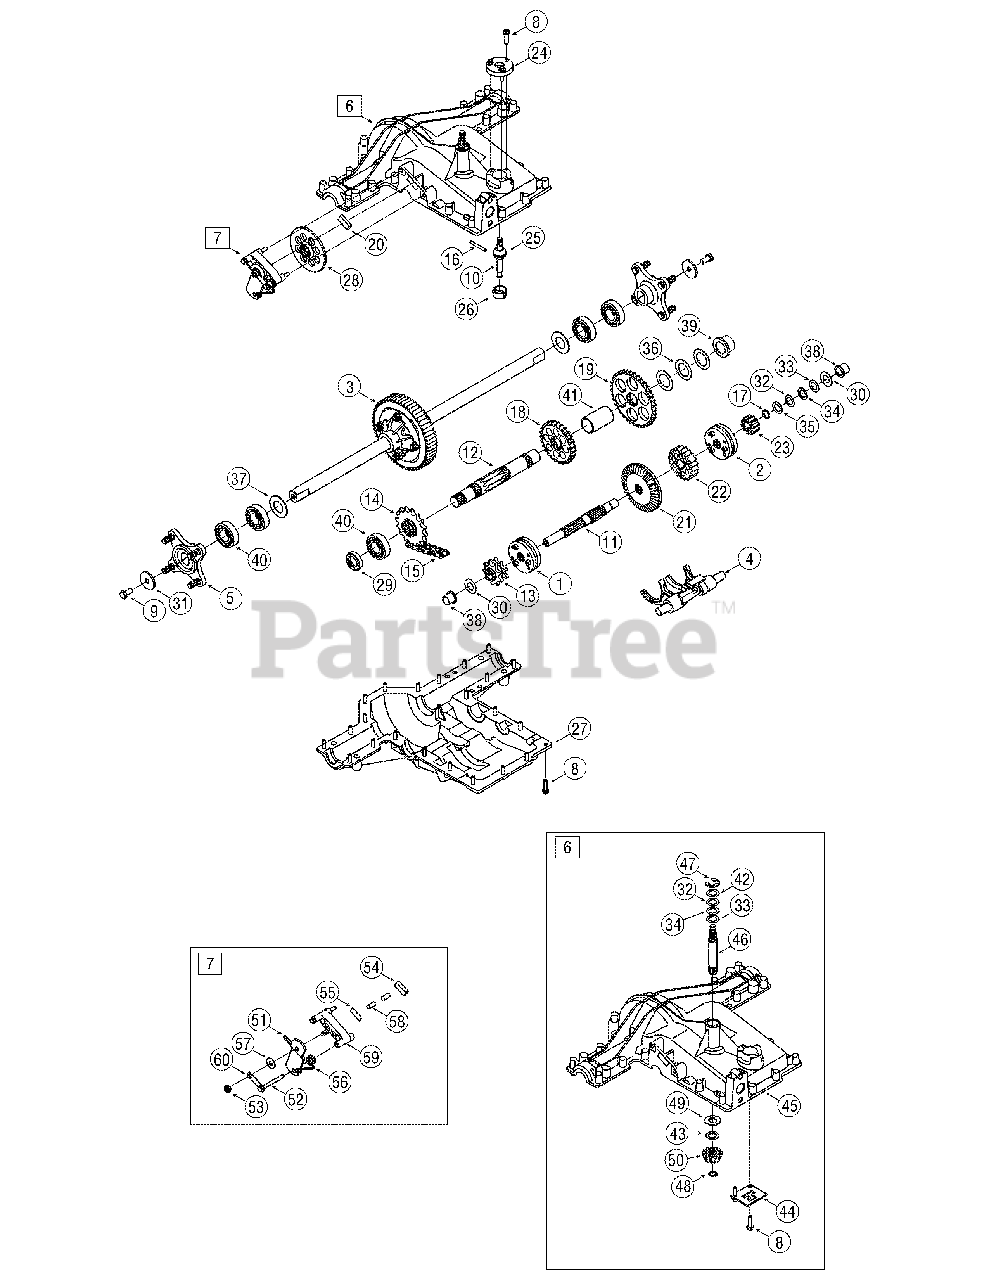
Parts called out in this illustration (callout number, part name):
1	Reverse Collar Assembly
2	Hi-Lo Collar Assembly
3	Differential Axle Assembly
4	Shift Fork Assembly
5	Wheel Hub Assembly
6	Upper Housing
7	Brake Assembly
8	Screw 1/4-20 x 1.0
9	Lock bolt 3/8-16 x 0.75
10	Shift lever
11	Drive Shaft
12	Output Shaft
13	9-tooth Sprocket
14	16-tooth Sprocket
15	22-link Chain,.625
16	Dowel Pin
17	External Snap Ring
18	27-tooth Spur Gear
19	37-tooth Spur Gear
20	Brake Pad
21	41-tooth Bevel Gear
22	20-tooth Spur Gear
23	10-tooth Spur Gear
24	Shift Cover
25	Spherical Bearing
26	Shifter Insert
27	Lower Transmission Housing
28	Disc Brake
29	Oil Seal
30	Washer, Flat, .656 X 1.25 X .02
31	Flat Washer
32	Flat Washer, 5/8 x 1.0 x.030*
33	Flat Washer, 5/8 x 1.0 x.040*
34	Flat Washer, 5/8 x 1.0 x.020*
35	Flat Washer, .632 X 1.00 X .035
36	Flat Washer, 1.12 X 1.75 X .03
37	Flat Washer, 1.010 X 1.56 X .060
38	Flanged Bearing
39	Flanged Bearing
40	Ball Bearing
42	Thrust Washer, 1.00 X .632
43	Flat Washer, .632 X 1.00 X .035
44	Lockout Plate
45	Upper Housing
46	Input Shaft
48	Retainer Ring
49	Thrust Washer, .635 X 1.26 X.06
50	13-tooth Bevel Gear
51	Brake Arm Actuator
52	Screw, 1/4-20 x 2.375
53	Hex Lock Nut, 5/16-24
54	Brake Pad
55	Puck Plate
56	Torsion Spring, .75 x 3 coils
57	Flat Washer, .343 x .880 x .062
58	Actuating Pin 5/16 dia.
59	Brake Yoke
60	Anti-Rotation Brake Bracket
